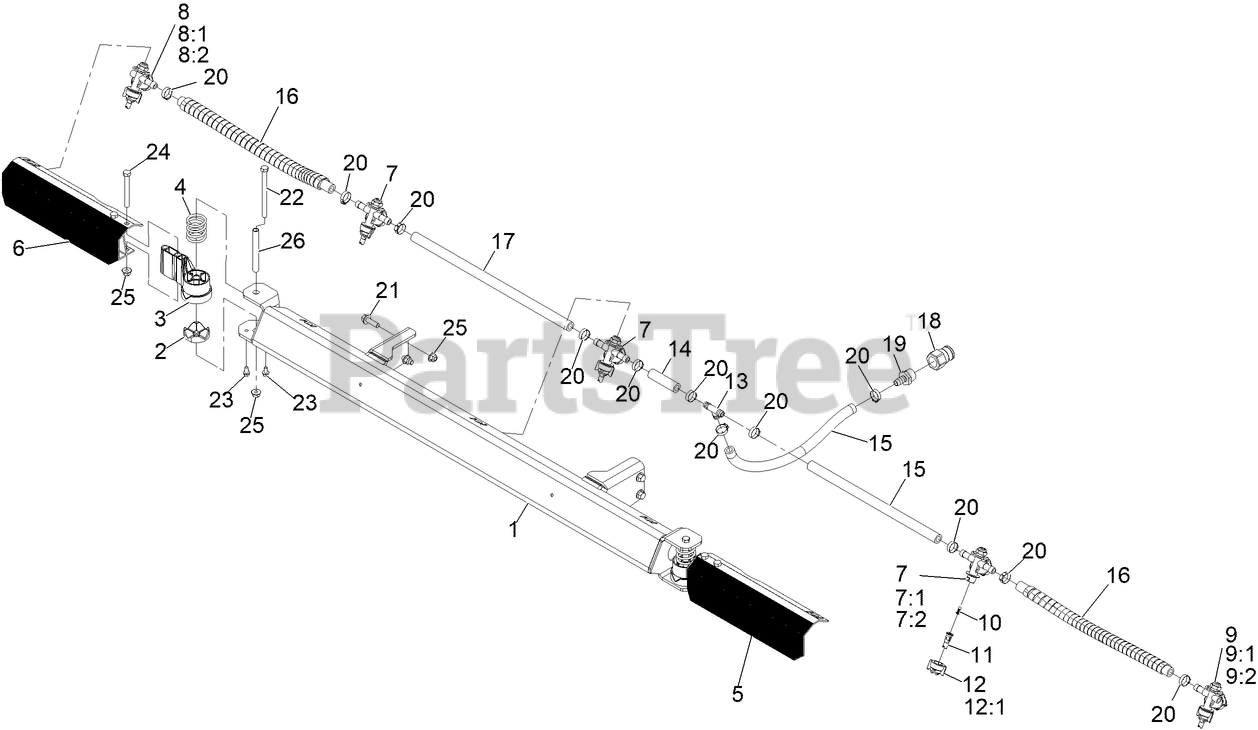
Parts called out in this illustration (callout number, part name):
1	WLD-BOOM CENTER
2	BOOM-PIVOT
3	HINGE-BOOM
4	SPRING-COMPRESSION
5	BOOM-WING, LH
6	BOOM-WING, RH
7	BODY-NOZZLE, CENTER
7:1	DIAPHRAGM FOR CHECK VALVE
7:2	CAP-DIAPHRAM
8	BODY-NOZZLE, RIGHT
8:1	CAP-SPRAYER NOZZLE
8:2	DIAPHRAGM-SPRAYER NOZZLE
9	BODY-NOZZLE, LEFT
9:1	CAP-DIAPHRAM
9:2	DIAPHRAGM FOR CHECK VALVE
10	STRAINER-NOZZLE, 50M 5PSI
11	TIP-SPRAY, 025
12	CAP-NOZZLE
12:1	SEAT-GASKET
13	FITTING-TEE, BARB
14	HOSE-SPRAY
15	HOSE-SPRAY
16	Hose-Spray, Wrapped
17	Hose-Spray
18	ADAPTER-MALE
19	FITTING-STRAIGHT
20	CLAMP-OETIKER, 167
21	SCREW-HHF
22	SCREW-HH
23	SCREW-HHF
24	SCREW-HH
25	Nut-Hex Flange
26	SPACER-BOOM, PIVOT
